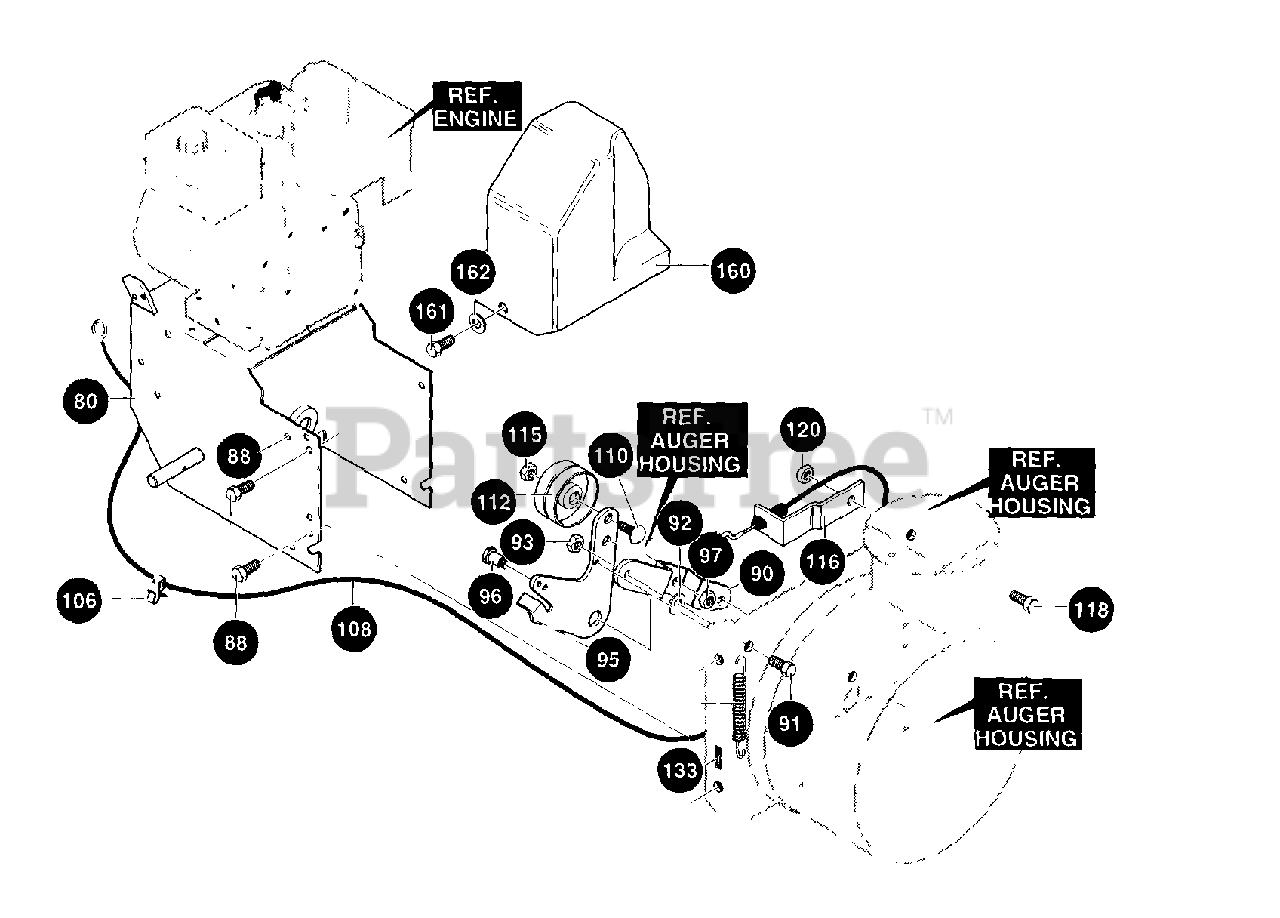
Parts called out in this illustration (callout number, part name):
80	Frame Assy
88	Screw, 5/16-18 x .75
90	Plate-Clutch Arm
91	Screw, 3/8-16 x .75
92	Washer, Regsptlk
93	Nut, 3/8-16
95	Arm-Clutch
96	Bolt, .497 x .138
97	Nut, 3/8-16 Reghexctrlk
106	Clip, Cable
108	Cable, Auger Clutch Ctrl
110	Screw, 3/8-16 x 1.25
112	Pulley, Idler
115	Nut, 3/8-16 Hexctrtlkjam
116	Bracket, Compact Cable
118	Screw, 3/8-16 x 1.25
120	Nut, 3/8-16 Reghexctrlk
133	Spring, Idler
160	Cover, Belt
161	Screw, 1/4-20 x .63
162	Flatwasher, .281 x .63 x .06
